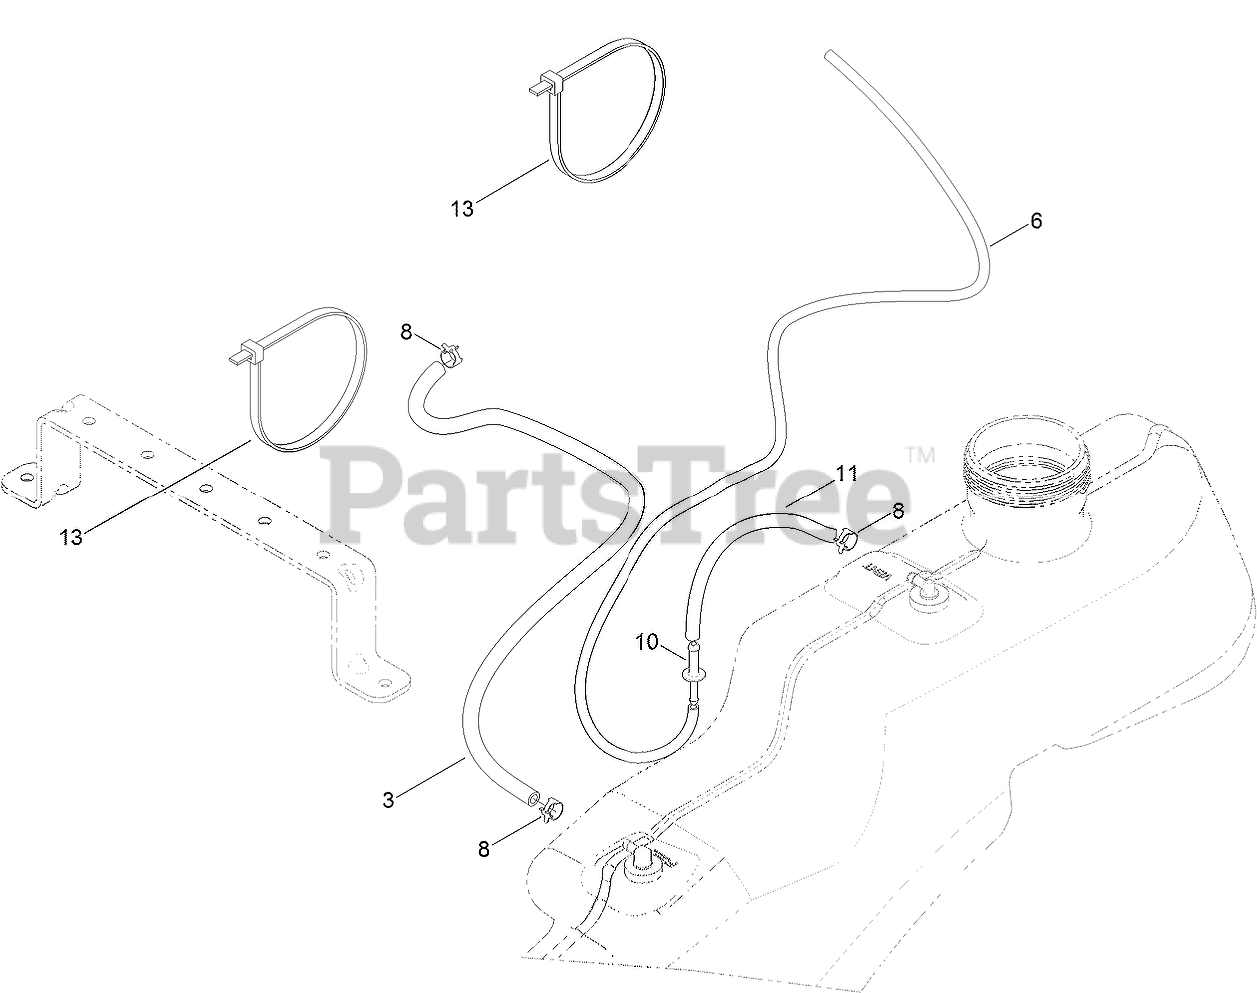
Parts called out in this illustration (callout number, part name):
3	HOSE-FUEL
6	HOSE-FUEL
8	CLAMP-HOSE
10	ADAPTOR-ORIFICE
11	HOSE-FUEL
13	TIE-CABLE
